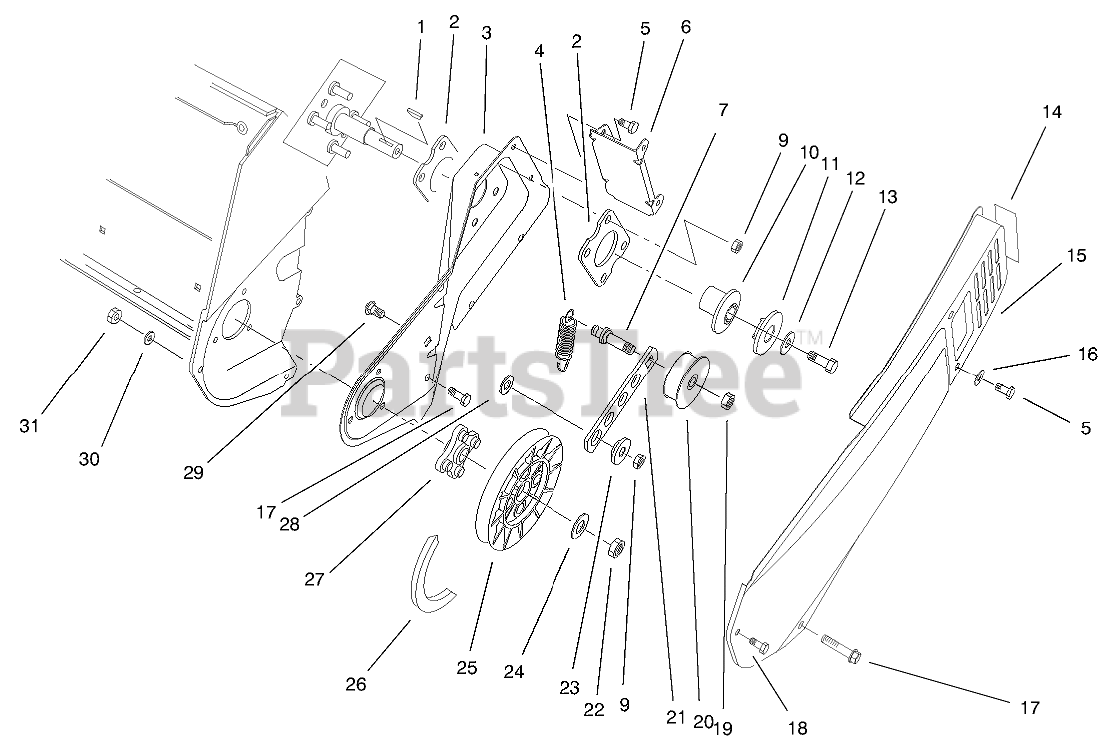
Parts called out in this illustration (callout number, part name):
1	KEY-WOODRUFF
2	PLATE-ENGINE
3	SIDEPLATE-LH
4	SPRING-EXTENSION
5	SCREW-HWH
6	BRACKET-COVER, BELT
7	PIN-IDLER
9	NUT-LOCK, NI
10	Hub-HALF SHEAVE
11	CAP-HALF SHEAVE
12	WASHER-FLAT
13	SCREW-HH
14	Decal-Hot
15	COVER-BELT
16	WASHER-FLAT
17	SCREW-PLASTIC
19	NUT-LOCK, NI
20	PULLEY-IDLER
21	ARM-IDLER
22	NUT-LOCK, NI
23	BUSHING-IDLER
24	WASHER-FLAT
25	PULLEY-DRIVEN
26	V-BELT
28	WASHER
29	SCREW-CARR
30	WASHER-FLAT
31	NUT-LOCK, NI
